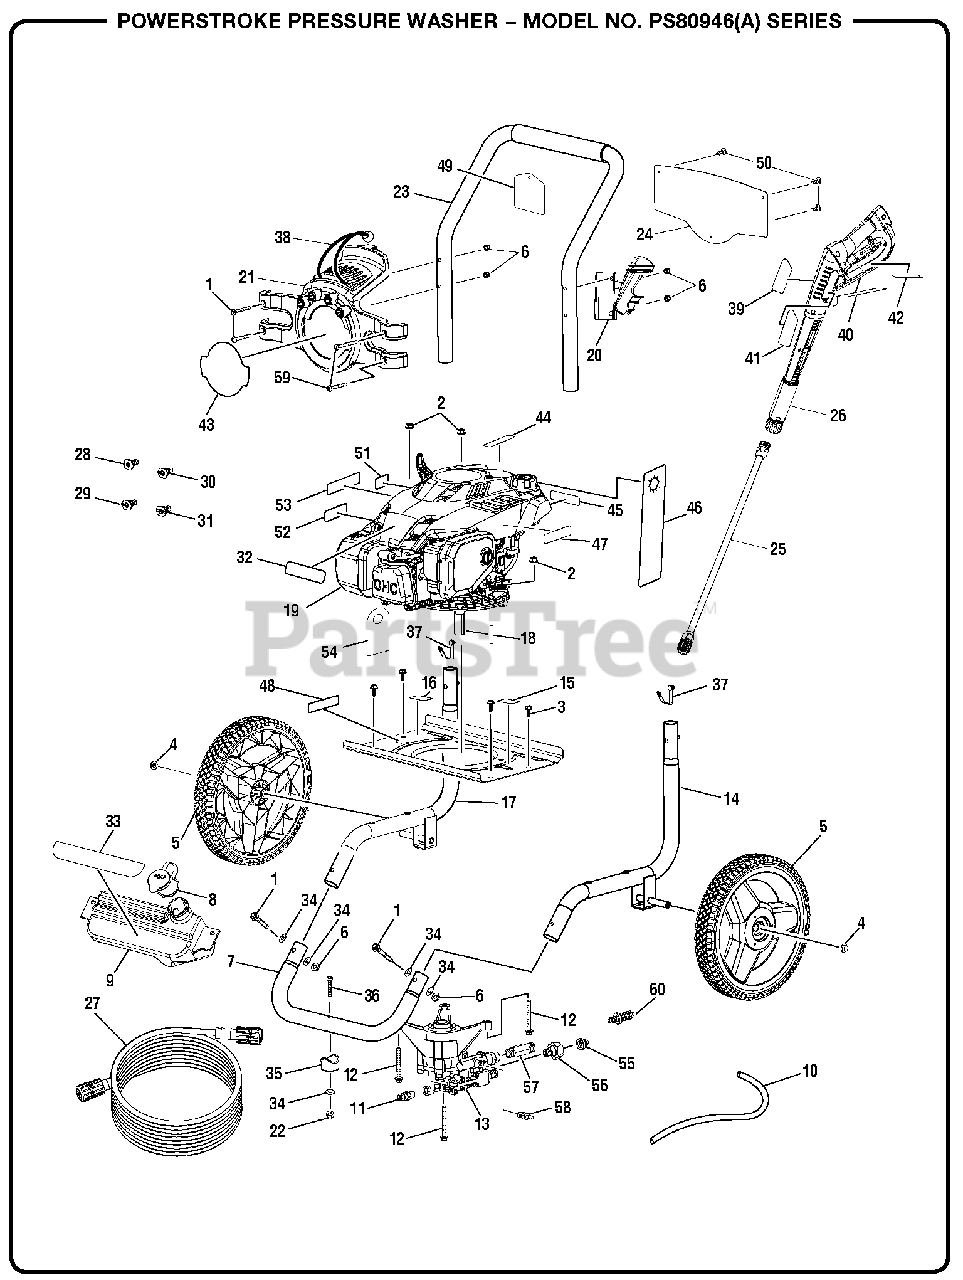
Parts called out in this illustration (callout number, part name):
1	Screw (M6 x 48 mm, T30 Torx Hd.)
2	Flange Nut (M8 x 1.25 in.)
3	Bolt (M6 x 16 mm, Flanged Hex Hd.)
4	Metal Cap
5	Wheel (12 in.)
6	Lock Nut (M6)
7	Front Frame Assembly
8	Soap Tank Cap
9	Soap Tank
10	Chemical Siphon Tube
11	Thermal Release Valve
12	Bolt (M8 x 60 mm, Flange Hd.)
13	Pump
14	Main Frame Assembly (Right)
15	Warning Label
16	Oil Fill Location Label
17	Main Frame Assembly (Left)
18	Output Shaft Key (35mm)
20	Wand Holder
21	Hose and Nozzle Assembly
22	Lock Nut (1/4-20)
23	Handle w/Foam
24	Quick Start Panel
25	Spray Wand Assembly
26	Trigger Handle Assembly
27	Hose (25 ft.)
28	Soap Nozzle
29	25deg Nozzle
30	40deg Nozzle
31	0deg Nozzle
32	Subaru Label
33	Detergent Tank Label
34	Washer (1/4 in.)
36	Screw (1/4-20 x 1.85 in., T30 Torx Hd.)
37	Spring Clip
38	Bungee Cord Assembly
39	Label (Trigger Handle Logo)
40	Label (Trigger Handle Specifications)
41	Label (Trigger Handle Warning)
42	Label (Trigger Handle Warning, French & Spanish)
43	Performance Label
44	E85 Label
45	Do Not Mix Label
46	Warning Hangtag
47	Engine Control Label
48	Data Label
49	Nozzle Hangtag
50	Screw (#6-20 x 3/8 in., T10 Torx Pan Hd.)
51	Lubricant Label
52	Hot Surface Label
53	Combustion Label
54	Oil Dipstick Hangtag
55	Filter Screen
56	Outlet Tube
57	Inlet Tube
58	Soap Injector Kit
59	Screw (M6 x 55 mm, T30 Torx Hd.)
60	Unloader Valve
